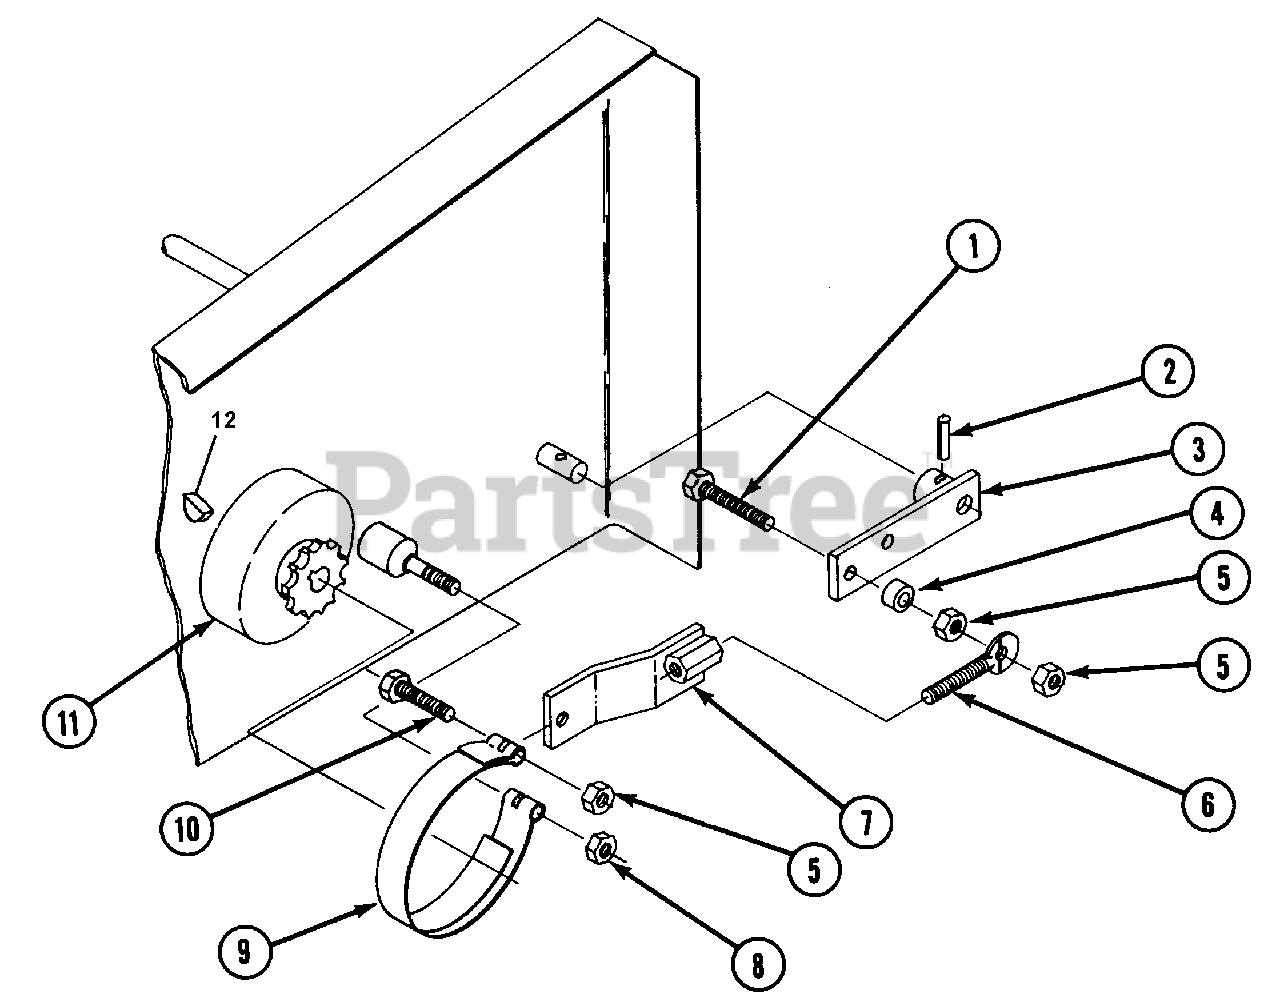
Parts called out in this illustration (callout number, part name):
1	CAPSCREW, 5/16-18 X 1-1/2
2	PIN, SPIROL, 3/16 X 1, LIGHT DUTY
3	BRAKE ARM WELDMENT
4	SPACER, BRAKE LINK
5	LOCKNUT, HEX 5/16-18, W/NYLOC
6	THUMBSCREW SWIVEL
7	BRAKE LINK WLDT.
8	LOCKNUT, HEX 3/8-16, W/NYLOC
9	BRAKE BAND, 4-3/16 DIA. 3/4 WIDE
10	CAPSCREW, 5/16-18 X 1-1/4
11	SPROCKET/BRAKE DRUM WLDT.
12	WOODRUFF KEY 404 1/8 X 1/2
